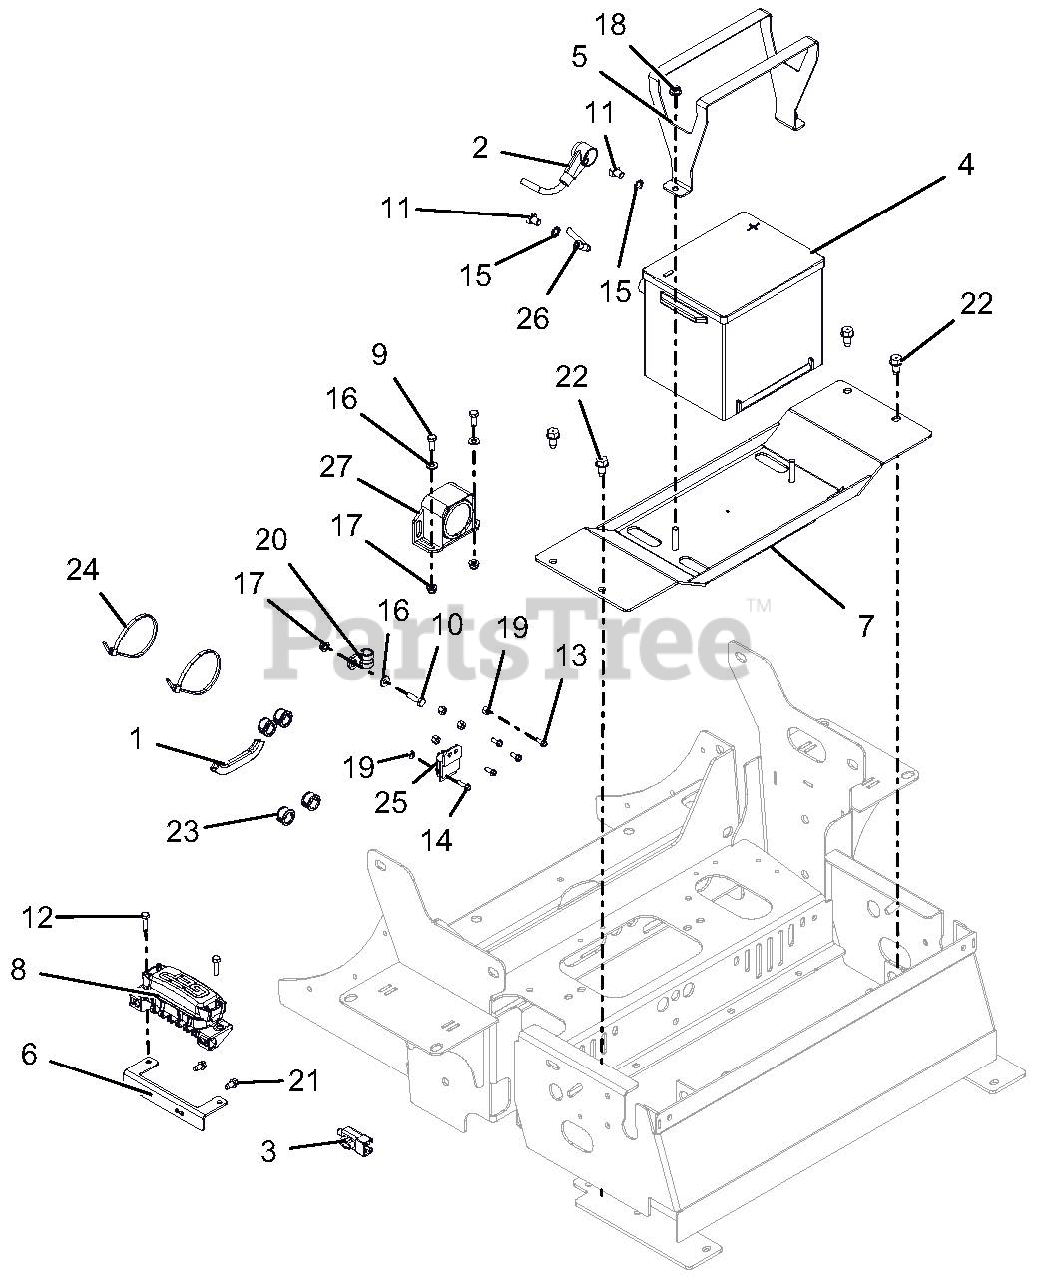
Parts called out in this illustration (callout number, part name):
1	STRIP, COWL
2	CABLE - POS BATT W/BOOTS 4X48
3	SWITCH, SNAP IN - N.O./N.O.
4	BATTERY-GROUP 70-540 CCA
5	BRACKET-BATTERY HOLD-DOWN
6	FUSE HOLDER MOUNTING BRKT -RED
7	PT400 DIESEL BATTERY TRAY -RED
8	WIRE HARNESS, PT400 DIESEL
9	@BLT-HEX .25-20X.75 GR5 YWZC
10	@BLT-HEX .25-20X1.00 GR5 YWZC
11	@BLT-HEX .38-16X.50 GR5 YWZC
12	@BLT-HEX M6-1.0X25 YWZC
13	@SCR-MCH 10-24X.50 HWH YWZC
14	@SCR-MCH 10-24X.75 HWH YWZC
15	@WSHR-LK-EXT.391X.628X.036YWZC
16	@WSHR-FL-STL.281X.62X.065 YWZC
17	@NUT-LK-NYL-FLG .25-20 YWZC
18	@NUT-SPNLK-FLG .312-18 YWZC
19	@NUT-LK-NYL 10-24 W/INSRT YWZC
20	CLAMP, CUSHIONED STEEL
21	SCR-TAP .25-20X.50 HWH TR YWZ
22	@SCR-TAP .38-16X.75 HWH TR YWZ
23	BUSH, PANEL SNAP .687X.875X.56
24	CABLE TIE LG 5-1/2
25	MODULE,INTERLOCK,DELAY, 1801
26	CABLE, NEGATIVE BATTERY 49.00
27	ALARM,BACKUP BA1A W/ NO GROUND
